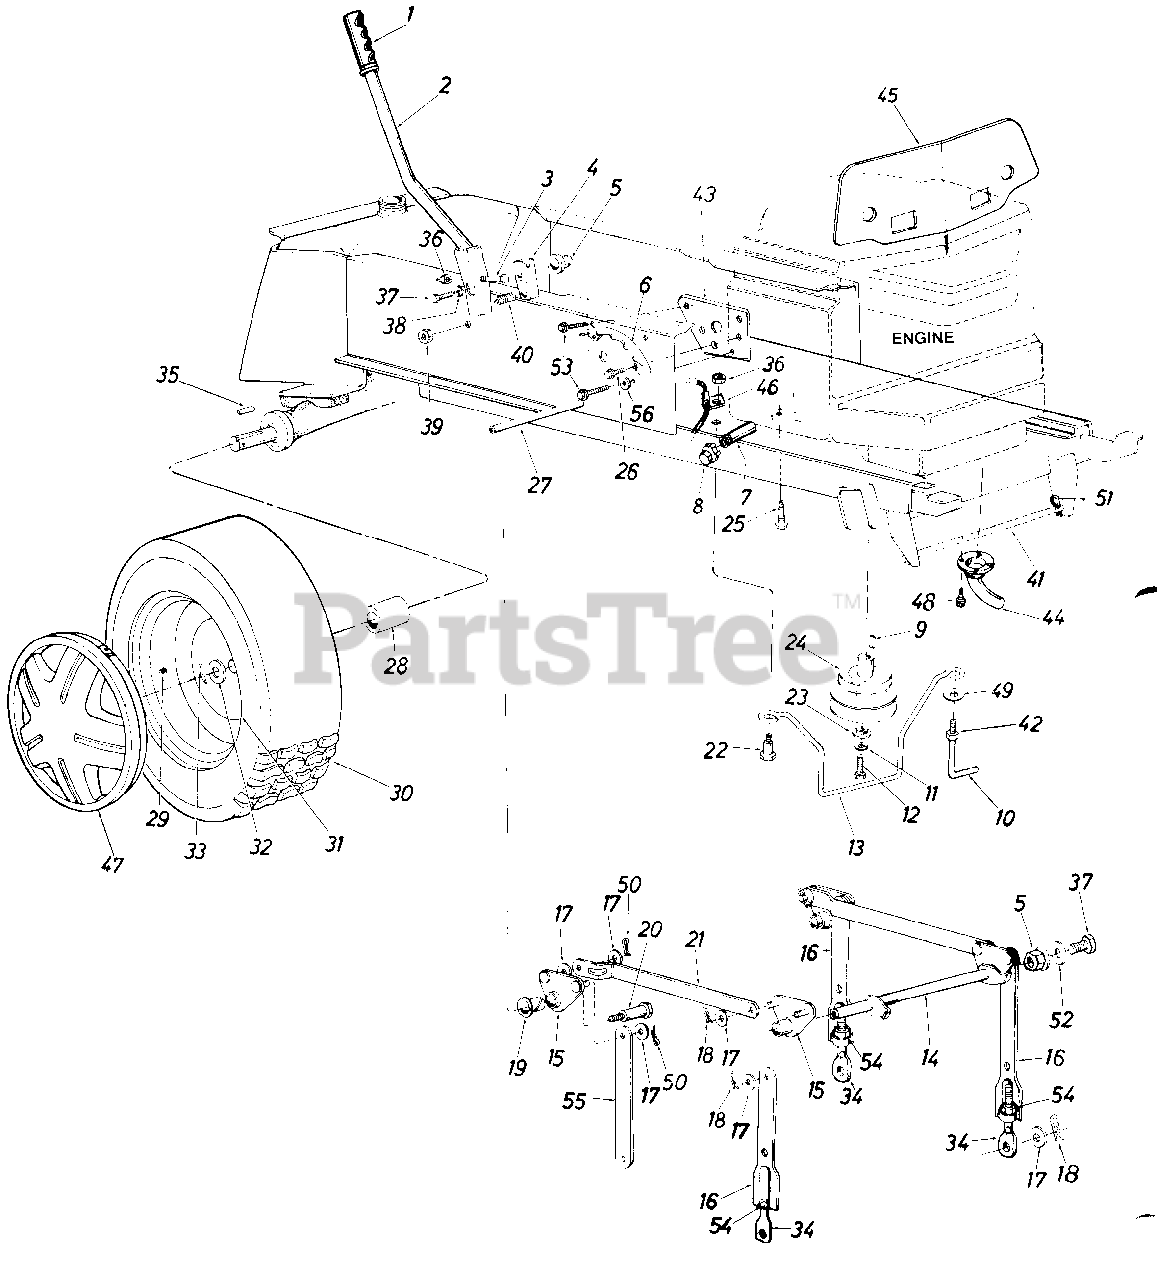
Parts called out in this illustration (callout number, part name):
1	Grip
2	Lift Handle Ass'y.
3	Hex Bolt 5/16-18 x 1.5" Lg.*
4	Lift Shaft Drive
5	Plastic Hex Brg. 5/8" I.D.
8	Pipe Cap 3/8-18 Npt.
9	Sq Key 1/4" x 1/4" x 1.50" Lg.
10	Belt Guard Lock Pin
11	L-Wash. 7/16" I.D.
12	Hex Scr 7/16-20 x 1.50" Lg.
13	Belt Guard
14	Lift Shaft Ass'y.
15	Lift Pivot Brkt. Ass'y.
17	Fl-Wash. 1/2" I.D. x 1.00" O.D. x .090"
18	Hairpin Cotter
19	Nyliner 5/8" I.D. x .88" Lg.
20	Shld. Bolt 5/8" Dia. x .96" Lg. 3/8-16
23	Flat Wash. .44" .D. x 1.25" O.D. x .17"
24	Two-Step Engine Pulley 4.75" & 5.56"
25	Hex Wash. Hd. Scr. 3/8-16 x 1.25" Lg.
26	Hex Thd. Rolling Scr. 5/16-18 x .75" Lg.
27	Running Board Rod
28	Spacer 1.0" I.D. x 1.25" O.D. x 2.12" Lg.
29	Air Valve
33	Cotter Pin 3/16" Dia. x 1.50" Lg.
34	Eye Bolt Adj. Link 1/2-13 Thd.
35	Sq. Key 1/4 x 3.0"
36	Hex Cent. L-Nut 5/16-18 Thd.
37	Hex Scr. 5/16-24 x .62" Lg.*
38	L-Wash. 5/16" I.D.*
39	Hex Top L-Nut 3/8-16 Thd.
40	Compression Spring
41	Deck Connecting Rod
42	Hex Nut 5/16-24 Thd.*
43	Index Brkt. Reinforcement Plate
44	Exhaust Pipe
45	Heat Shield
46	Mounting Clamp
47	Hub Cap Rear
48	Hex Wash. Hd. AB-Tap Scr. #10 x .50" Lg.
49	Bell-Wash. .39" I.D.
50	Cotter Pin .09 Dia. x 1.0" Lg.
51	Int. Cotter Pin
52	Flat Wash. .34" I.D. x 1.12" O.D. x .125"
53	Hex Wash. Hd. AB-Tap Scr. 5/16-24 x .5" Lg.
54	Hex Nut 1/2-13 Thd.
56	Fl-Wash. .344" I.D.
